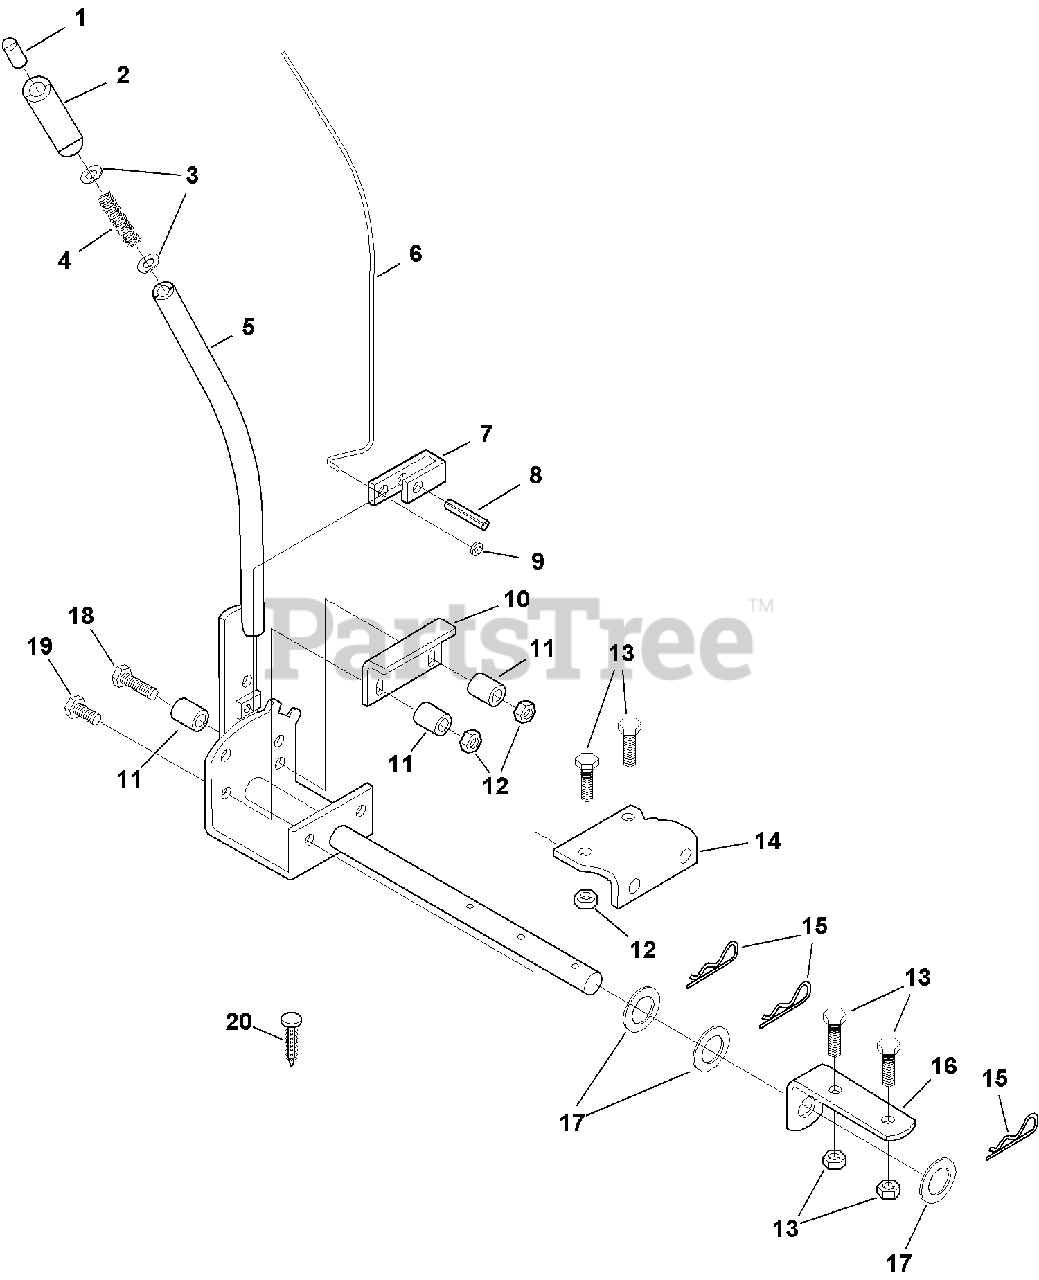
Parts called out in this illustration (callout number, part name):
2	GRIP, Black
3	WASHER, 5/16
4	SPRING, Compression
5	QUADRANT & LEVER ASSEMBLY
7	LATCH, Lift Lever
8	ROLL PIN, 3/8 x 1
10	BRACKET
12	NUT, ESNA, Hex Lock, 5/16-18
13	CAPSCREW, Hex Head, 5/16-18 x 7/8
14	BRACKET & PINS ASSEMBLY
15	CLIP, Hair Pin
17	WASHER
18	CAPSCREW, Hex Head, 5/16-18 x 1-3/4
19	CAPSCREW, Hex Head, 5/16-18 x 1-1/4
20	FASTNER, Footrest Mat
